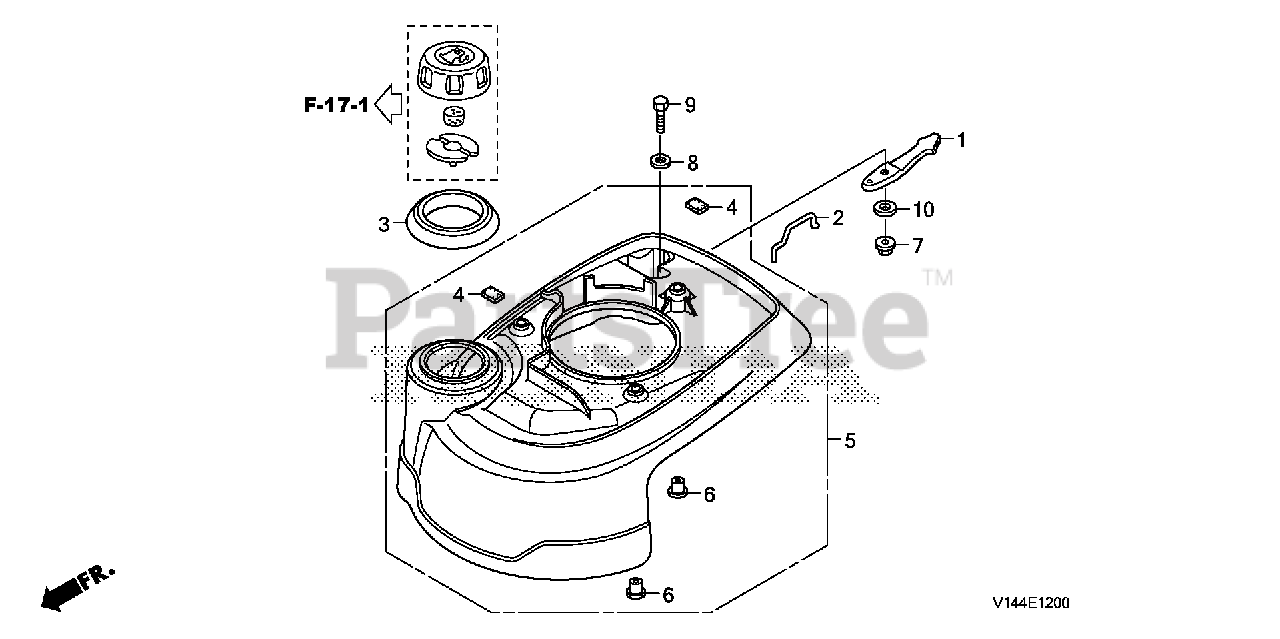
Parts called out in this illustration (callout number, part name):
1	LEVER, CHOKE
2	ROD, CHOKE
3	SEAL, FUEL FILLER NECK
4	CUSHION, FUEL TANK
5	COVER, FAN
6	COLLAR, FAN COVER
7	NUT, SELF-LOCK (5MM)
8	WASHER (5MM)
9	BOLT, HEX. (5X22)
10	WASHER, PLAIN (8MM)
